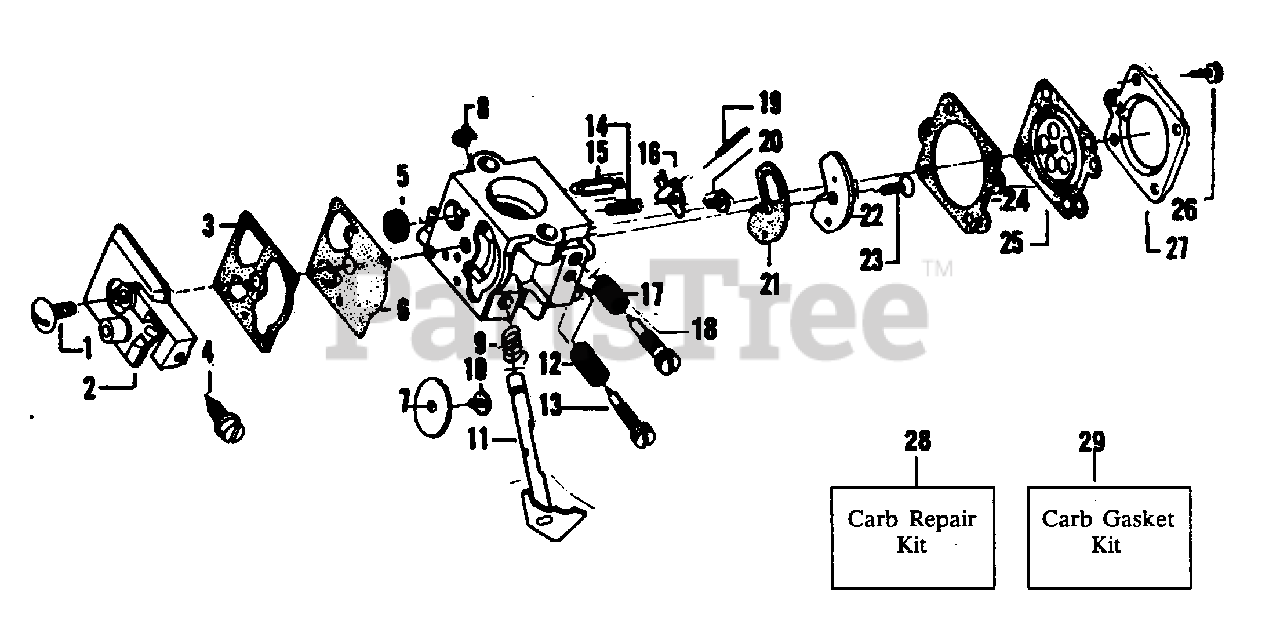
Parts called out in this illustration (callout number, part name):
1	Pump Cover Screw
2	Pump Cover Ass'y. (Inc. #4)
3	Pump Gasket
4	Idle Adjustment Screw
5	Inlet Screen
6	Diaphragm Pump
7	Throttle Valve
8	Throttle Shaft Clip
9	Throttle Return Spring
10	Throttle Valve Screw
11	Shaft Ass'y. - Throttle
12	Idle Needle Spring
13	Idle Needle
14	Metering Lever Spring
15	Inlet Needle Valve
16	Metering Lever
17	Hi Speed Needle Spring
18	Hi Speed Needle
19	Metering Lever Pin
20	Metering Lever Pin Screw
21	Circuit Plate Gasket
22	Circuit Plate
23	Circuit Plate Screw
24	Metering Diaphragm Gasket
25	Metering Diaphragm Ass'y.
26	Metering Cover & Throttle Shaft Clip Ass'y. Screw
27	Metering Diaphragm Cover
28	Carb Kwik Repair Kit
29	Carb. Gasket/Diaphragm Kit
